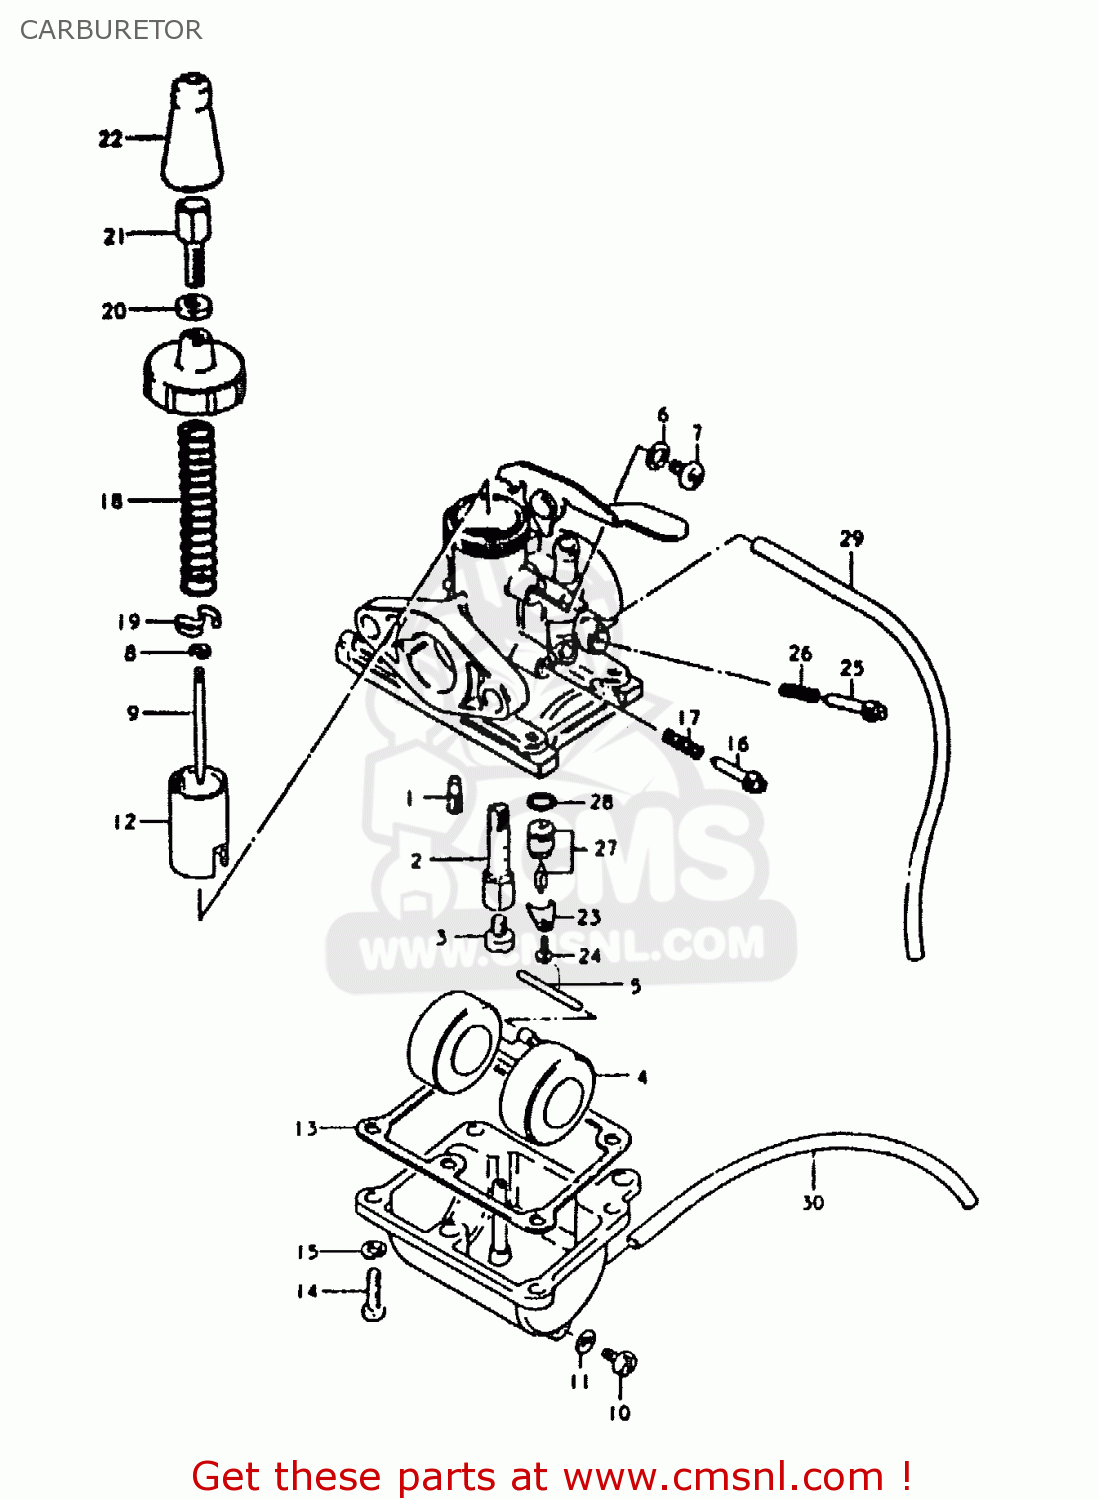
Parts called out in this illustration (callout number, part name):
1	JET,PILOT
2	JET, NEEDLE (E-7)
3	JET,MAIN(70)
4	FLOAT
5	PIN,FLOAT
6	RING
7	SCREW
8	CLIP,NEEDLE
9	NEEDLE,JET
10	PLUG
11	GASKET,DRAIN,PLUG (NAS)
12	VALVE,THROTTLE(CA:2.0)
13	GASKET,FLOAT CHAMBER (NAS)
14	SCREW
15	LOCK WASHER
16	SCREW,THROTTLE STOP
17	SPRING
18	SPRING,THROTTLE VALVE RETURN
19	PLATE,THROTTLE VALVE
20	NUT
21	ADJUSTER,CABLE
22	CAP
23	PLATE,NEEDLE VALVE FITING
24	SCREW
25	SCREW,AIR
26	SPRING
27	VALVE ASSY,NEEDLE
28	O-RING,NEEDLE VALVE
29	HOSE
30	HOSE
